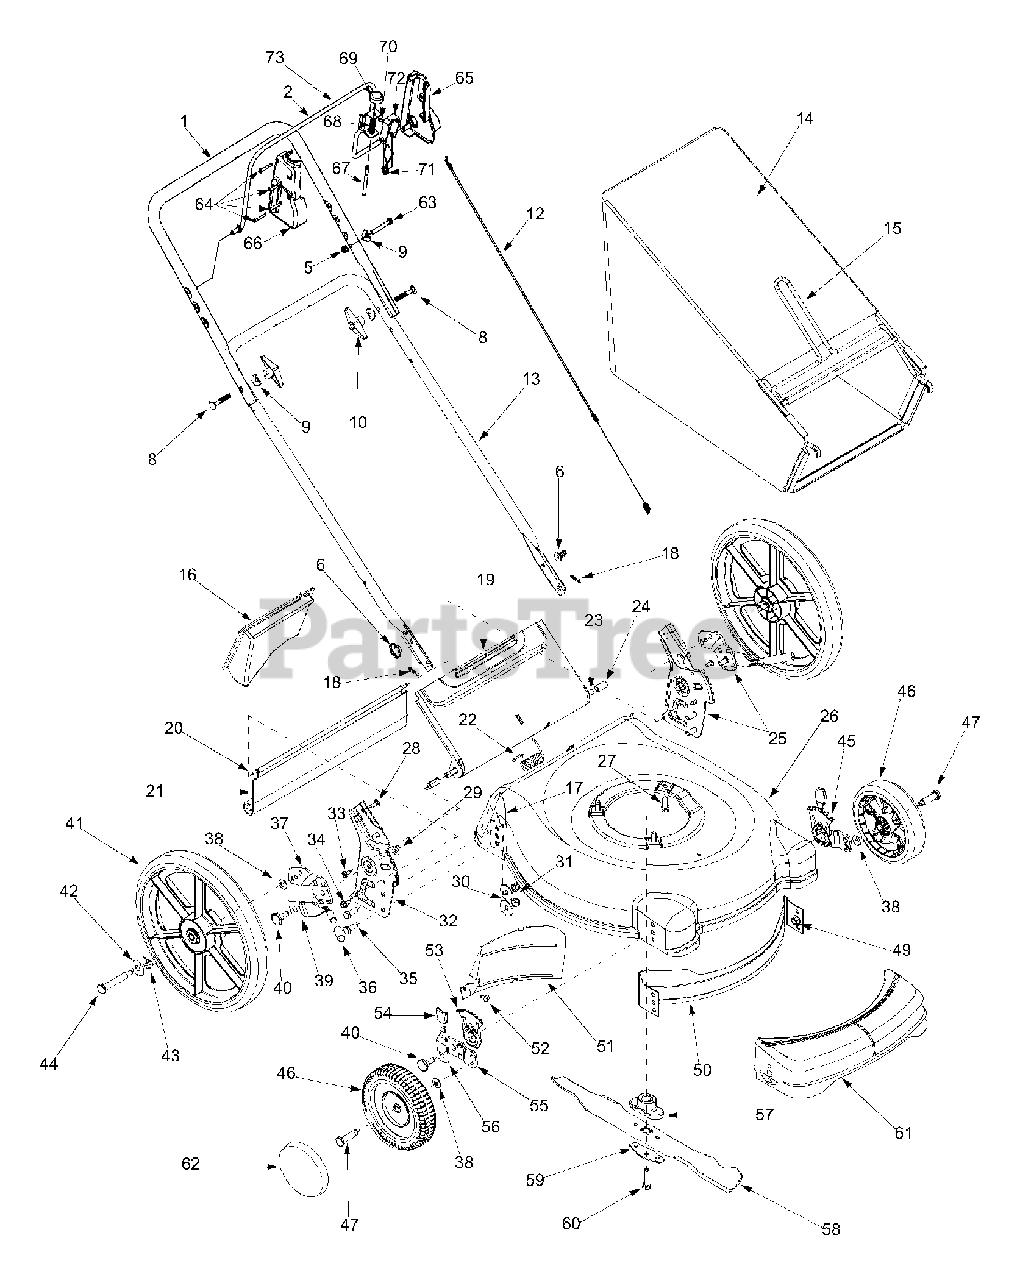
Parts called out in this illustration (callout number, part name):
6	Handle Knob
8	Carriage Bolt 5/16-18 x 2"
9	Shoulder Washer .320 ID x .930 OD
10	Wing Nut
12	Self Start Control Cable 58.25"
14	Grass Bag
16	Rear Mulch Plug
18	Hairpin Clip
21	Trailshield
22	Door Spring
23	Chute Door Pivot Rod
24	Spacer .375 O.D. x .50 I.D. x 1.02"
25	Handle Bracket Assembly - LH
28	Hex Carriage Screw 1/4-20
29	Flange Lock Nut 3/8-16
30	Bell Washer .390 ID x .380 OD
31	Hex Lock Nut 3/8-16
33	Machine Screw 1/4-20 x .500
34	Hex Washer Screw 1/4-14 x .625
35	Hex Cap Screw 3/8-16 x 1.0
36	Foam Grip
37	Pivot Bar - RH
38	Spring Washer .375 ID x .870 OD
39	Spring Lever
40	Shoulder Screw
41	Rear Wheel Assembly 14 x 2.1
42	Flat Washer .510 ID x 1.37 OD
43	Wave Washer .500 ID x 1.0 OD
44	Shoulder Screw
45	Front Height Adjuster - RH
46	Front Wheel Assembly 8 x 2.1
47	Shoulder Bolt
49	Flange Lock Nut 3/8-16
52	Tap Screw 1/4-14 x .625.
53	Height Adjustment Plate
54	Height Adjustment Knob
56	Spring Lever
57	Blade Adapter
58	21" Mulching
59	Blade Bell Support
60	Hex Cap Screw 3/8-24 x 1.5
61	Front End Cover
62	Hub Cap
63	Hex Hd. Cap Scr. 1/4-20 Gr.5
64	Hi-Low Screw
65	Control Cover LH
66	Control Cover RH
68	Compression Spring
69	Button
70	Retention Spring
71	Torsion Spring
72	Lever
